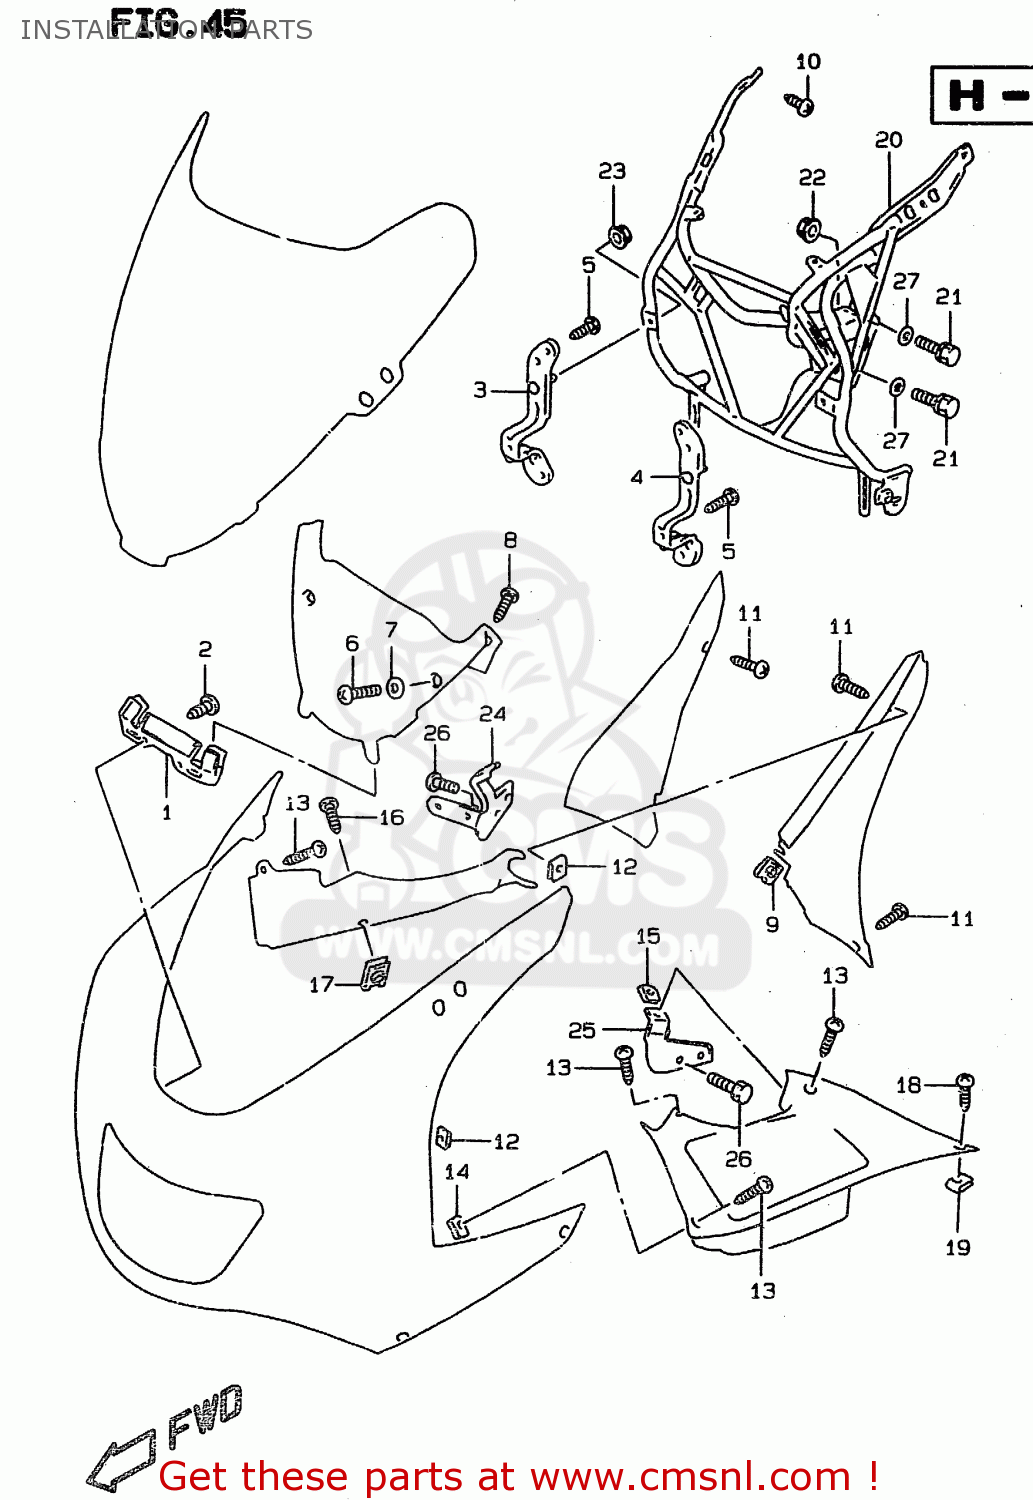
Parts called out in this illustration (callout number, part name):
1	BRACKET,WINDSCREEN FIT FR
2	SCREW 5X10
3	BRACKET,HEADLAMP FITING,R
4	BRACKET,HEADLAMP FITING,L
5	SCREW 5X10
6	SCREW 5X12
7	WASHER(5.2X14X1.5)
8	SCREW
9	NUT
10	SCREW 5X10
11	SCREW
12	NUT
13	SCREW
14	NUT
15	NUT
16	SCREW
17	NUT
18	SCREW
19	NUT
20	BRACE,COWLING
21	BOLT(8X40)
22	NUT
23	NUT
24	BRACKET,SIDE PANEL,R
25	BRACKET,SIDE PANEL,L
26	BOLT
27	WASHER
